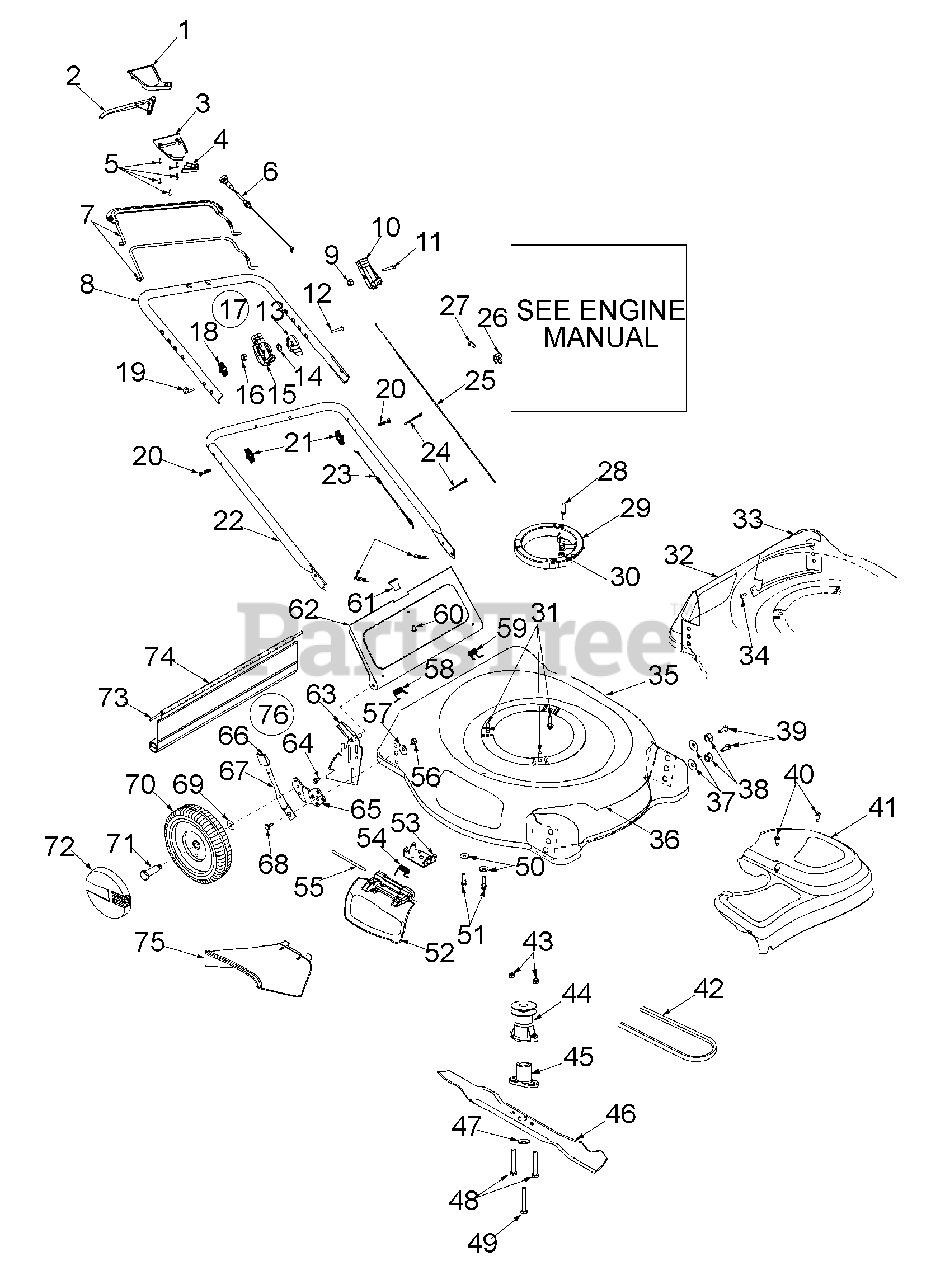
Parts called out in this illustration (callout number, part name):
1	Upper Drive Cover
2	Drive Lever
3	Lower Drive Cover
4	Mounting Cap
5	Screw #10-12: 75
6	Drive Cable
9	Hex Lock Nut 1/4-20
10	Throttle Hsg. w/o Lever
11	Scr. Oval C-Sunk 1/4-20 x 1.31
12	Scr. Oval C-Sunk 1/4-20 x 1.81 Scr. 1/4-20
13	Throttle Lever
14	Curved Washer .663 x .980 x .014
15	Throttle Housing
16	Hex Lock Nut 1/4-20 Thd.
17	Throttle Body Comp.
19	Eye Bolt 1/4-20
20	Carriage Bolt 5/16-18 x 2.0
21	Knob
23	Throttle Cable: 55" B&S
24	Tie Cable
25	Control Cable 39" B&S
26	Cable Clamp B&S
27	Hex Screw: T: #10-32 x .625 Lg. (B&S)
28	Pin-Belt Keeper
29	Engine Spacer
30	Hex Nut 1/4-20 Thread
31	Tapp Screw w/Hex Lock Wash
34	Scr. AB: 1/4-14 .625 Trust
38	Bell Washer .39 x 1.13 x .062
39	Hex Screw 3/8-16 x .75
40	Screw #12 x .457
41	Trans Cover - Black
42	V-Belt
43	Hex Lock Nut 1/4-20 Thd.
44	Drive Pulley
45	Blade Adapter Kit
46	21" Mulching Blade w/star
47	Bell Washer .396 x 1.140 x .095
48	Hex Screw 1/4-2 x 1.50
49	Hex Screw 3/8-24 x 2.50
50	Bell Washer .265 x .75 x .062
51	Tapp Screw 1/4-20 x .500
52	Mulch Plug Ass'y
54	Torsion Spring
55	Hinge Pin
56	Hex Nut 3/8-16
57	Bell Washer .39 ID x 1.38 OD
58	Torsion Spring - RH
59	Torsion Spring - LH
60	Scr. Tr. Mach #10-24 x .380
64	Hex Scr. w/wash. 1/4-14 x .62
65	Pivot Bar - RH
66	Knob
67	Spring Lever
68	Shldr Scr. .500 Dia x .434 Long
69	Bell Washer .380 x .880 x .062
70	Wheel 8 x 1.75 Disk Bar Grey
71	Shldr. Scr. .498 x 1.445
72	Hubcap: Euro Grey
73	Wire
74	Rear Flap
75	Chute Deflector
